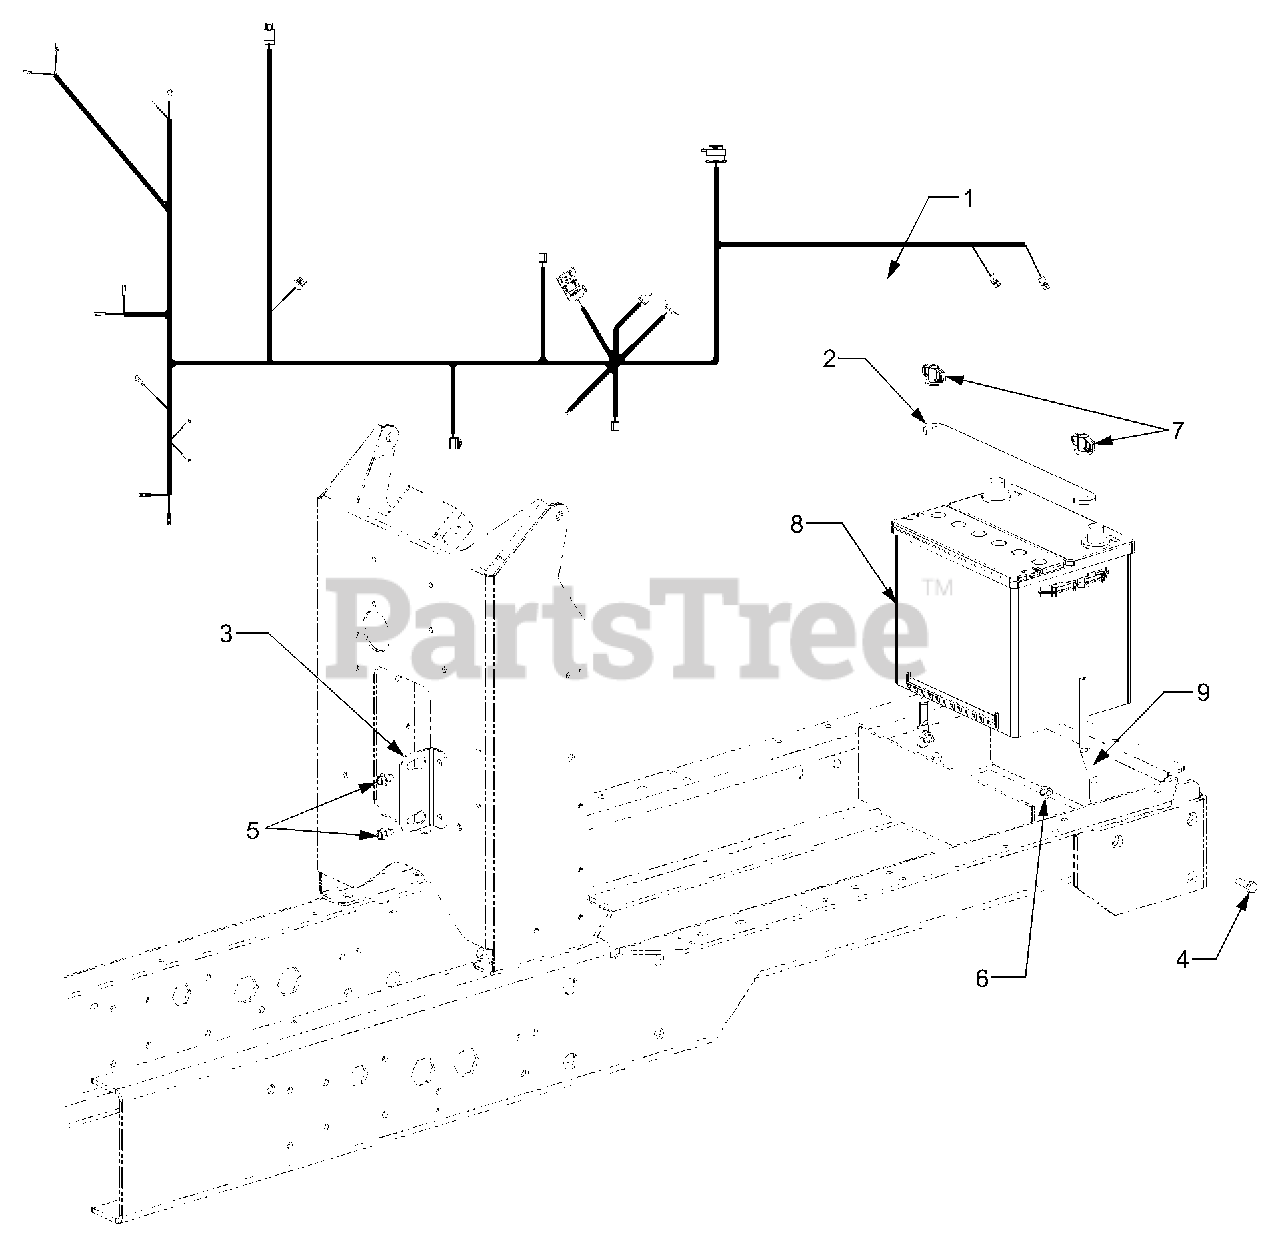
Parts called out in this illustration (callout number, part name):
1	Harness, Main Wire
2	Strap, Battery Holddown
5	Screw, Hex Wash Hd. Tapp 1/4-20 x .5
6	Nut, Hex Nylon Insert Lock, 1/4-20
7	Nut, Wing w/Bell Washer, 5/16-18
8	Battery, 500 cca Dry
9	Rod, Battery Holddown
